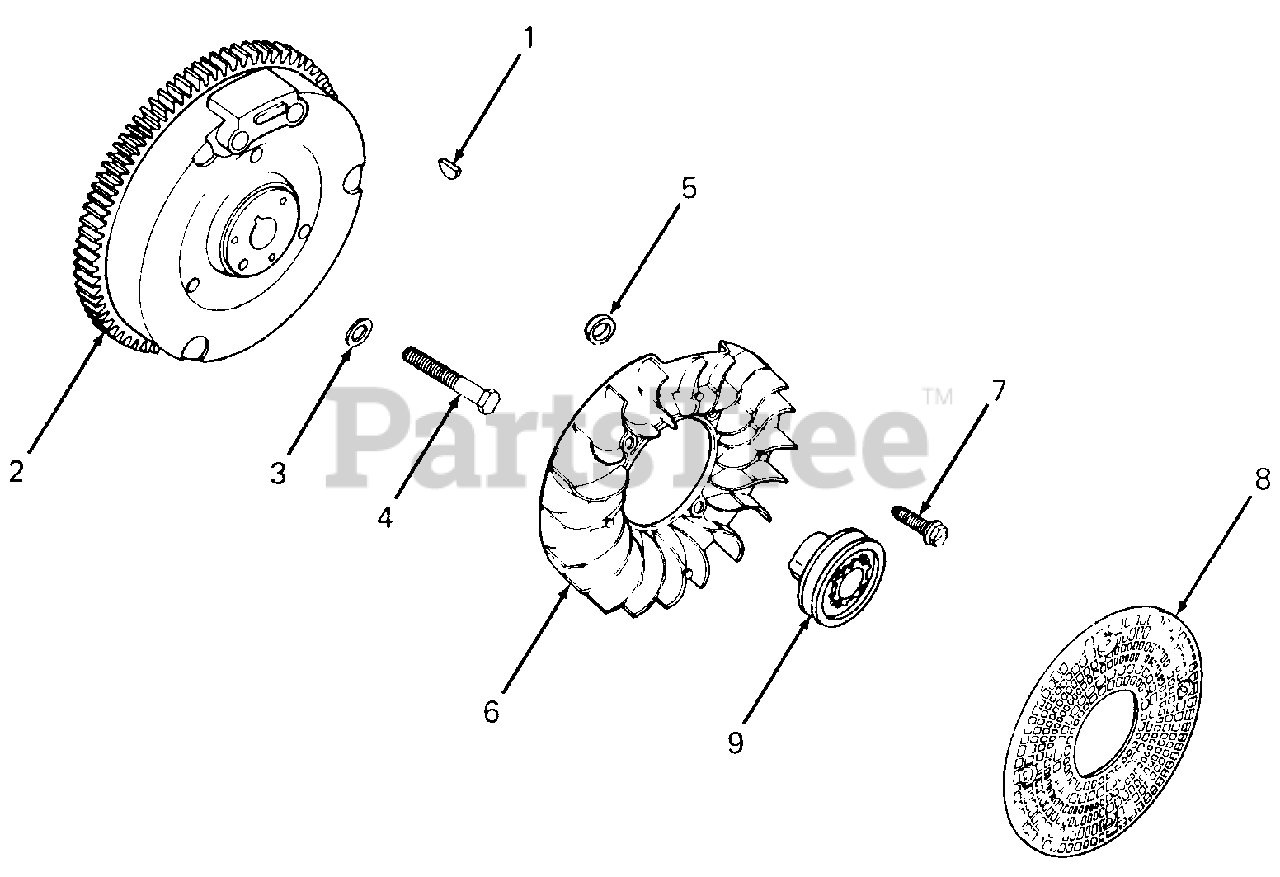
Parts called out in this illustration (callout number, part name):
3	Washer, Plain, 1-3/8 OD
4	Screw, Hex Mach, 3/8-24 X 1-1/8 Lg
5	Spacer, 1/4 ID, 3/8 OD, 15/64" Wd
7	Screw, Hex Wash Hd, 1/4-20 X 5/8 Lg
8	Screen, Grass
9	Cup, Front Drive
